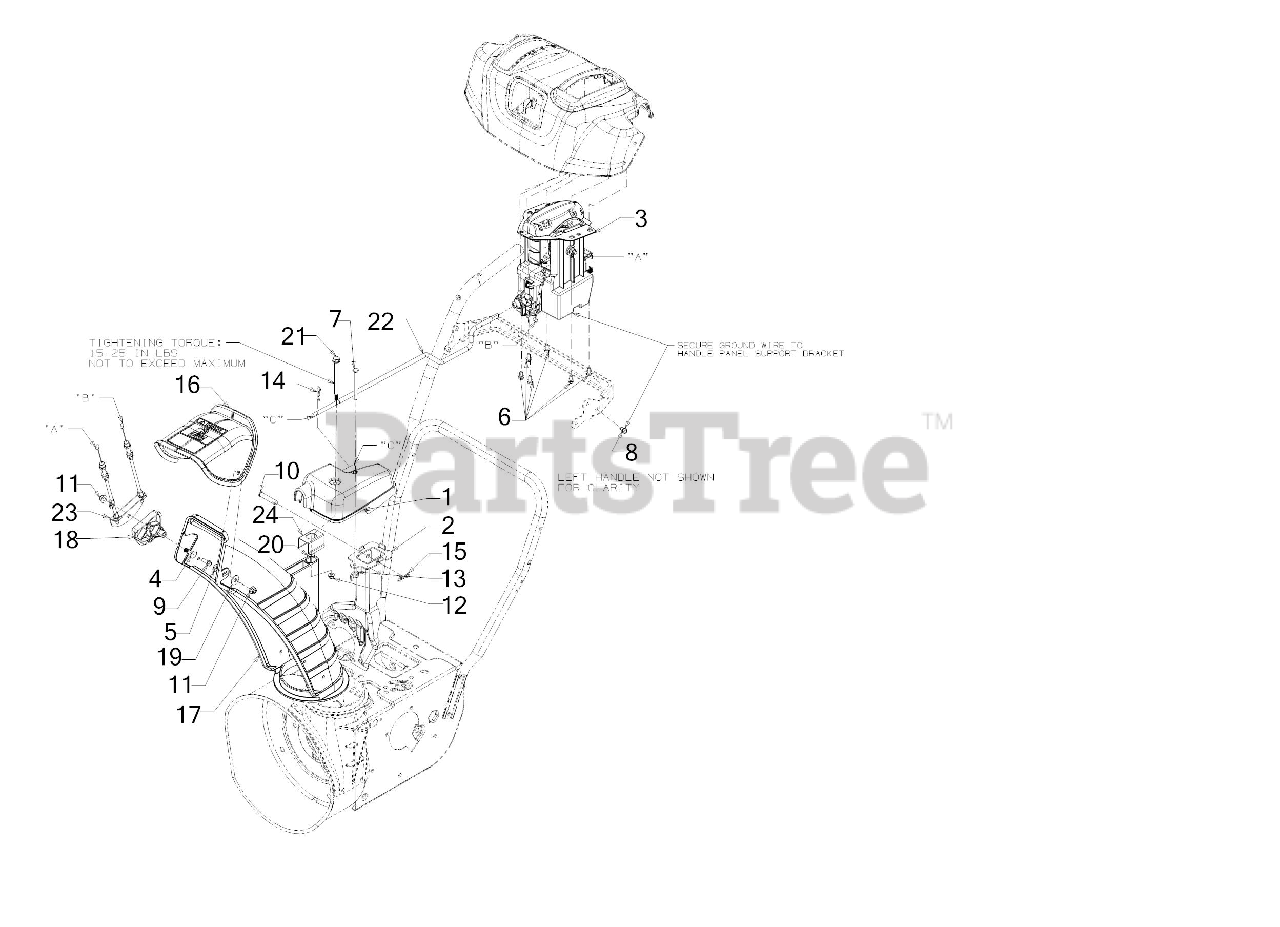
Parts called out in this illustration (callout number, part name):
1	WORM GEARBOX ASSEMBLY
2	CHUTE SUPPORT BRACKET ASSEMBLY
3	4-WAY CHUTE CONTROL ASSEMBLY
4	CARRIAGE BOLT 5/16-18 x 1.50
5	CARRIAGE BOLT 5/16-18 x 1
6	HEX SCREW 1/4-15 x .50
7	SCREW 1/4-20 x 3.0 GR5
8	SCREW 1/4-20 X.500
9	SCREW 1/4-15 x .750
10	CLEVIS PIN 3/8 x 1.87
11	FLANGE LOCK NUT 5/16-18
12	FLANGE LOCK NUT
13	WING NUT 1/4-20
14	INTERNAL COTTER PIN
15	BOW TIE COTTER PIN 1/4-5/16
16	UPPER REMOTE CHUTE WITH LABEL
17	LOWER CHUTE 5" DIA
18	CABLE CHUTE GUIDE
19	FLAT WASHER
20	FLAT WASHER
21	SHOULDER SCREW
22	ELECTRIC CHUTE CRANK ROD
23	CABLE BRACKET
24	CHUTE BRACKET
